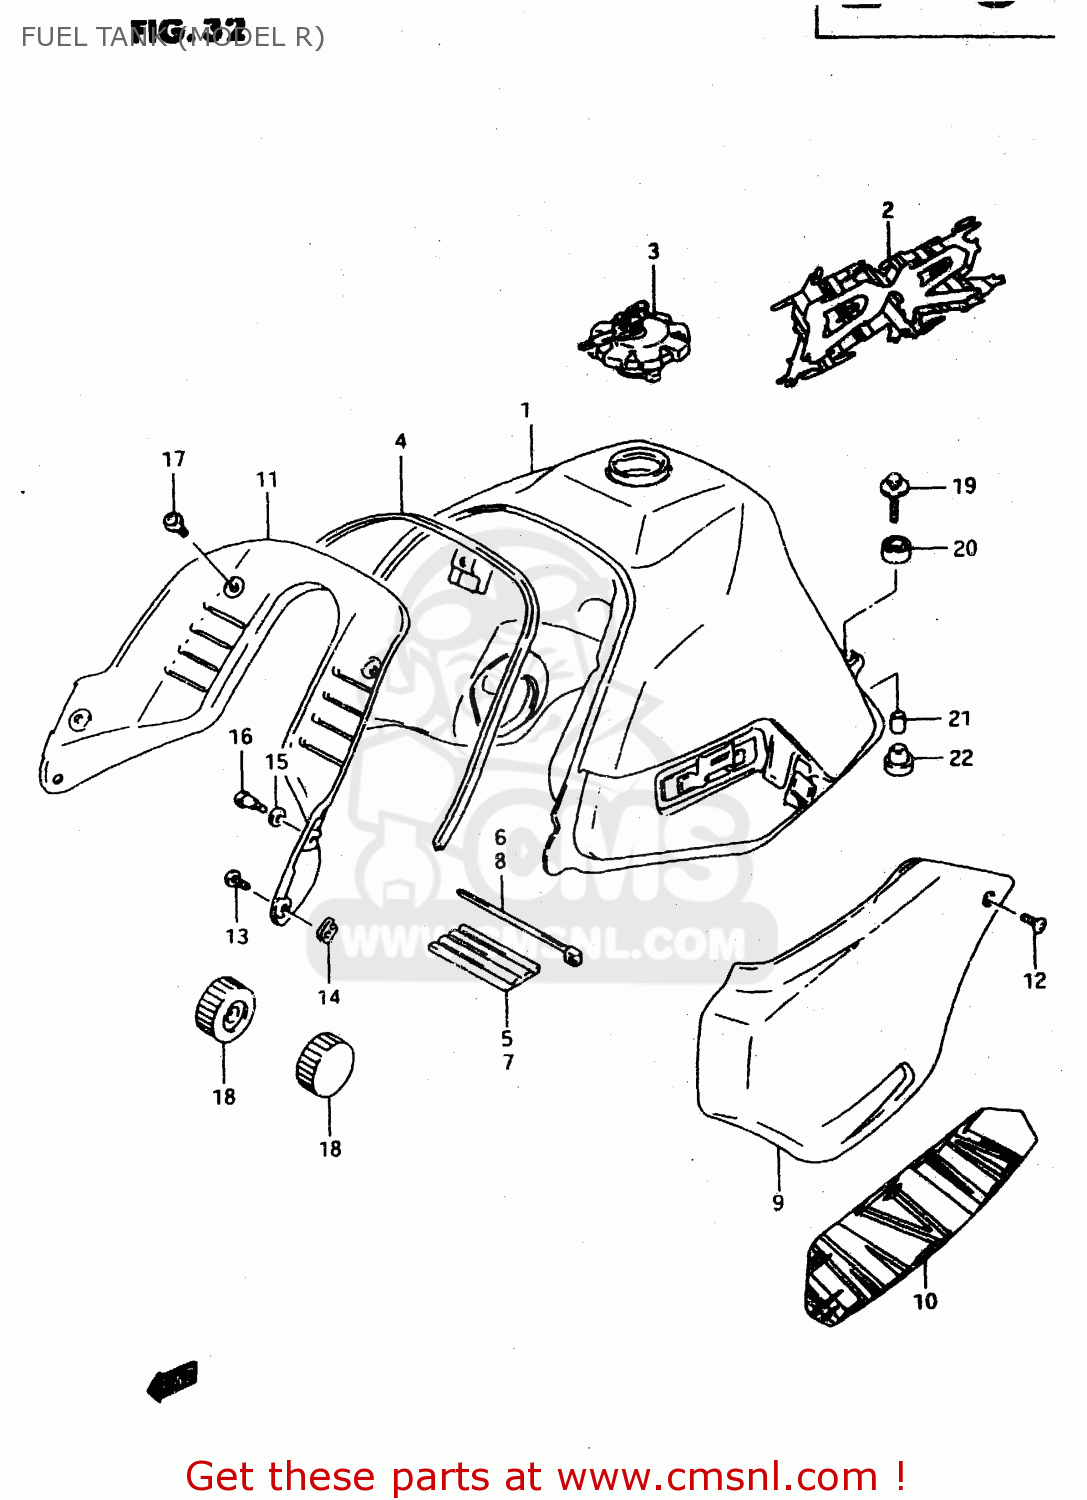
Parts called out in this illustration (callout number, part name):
1	TANK ASSEMBLY,FUEL
2	TAPE SET, FUEL TANK
3	CAP SET,FUEL TANK
4	MOLD,COWLING
5	CUSHION,FUEL TANK UPR FR
6	CLAMP
7	CUSHION,TANK UPR RR
8	CLAMP(L:300)
9	COVER,FUEL TANK,R
10	TAPE,TANK COVER,R
11	COVER,FUEL TANK,FRONT
12	SCREW
13	SCREW
14	NUT
15	WASHER (5.1X20X1.4)
16	SCREW(5X18)
17	SCREW
18	CUSHION,FUEL TANK FR
19	BOLT(6X30)
20	CUSHION
21	SPACER
22	CUSHION
